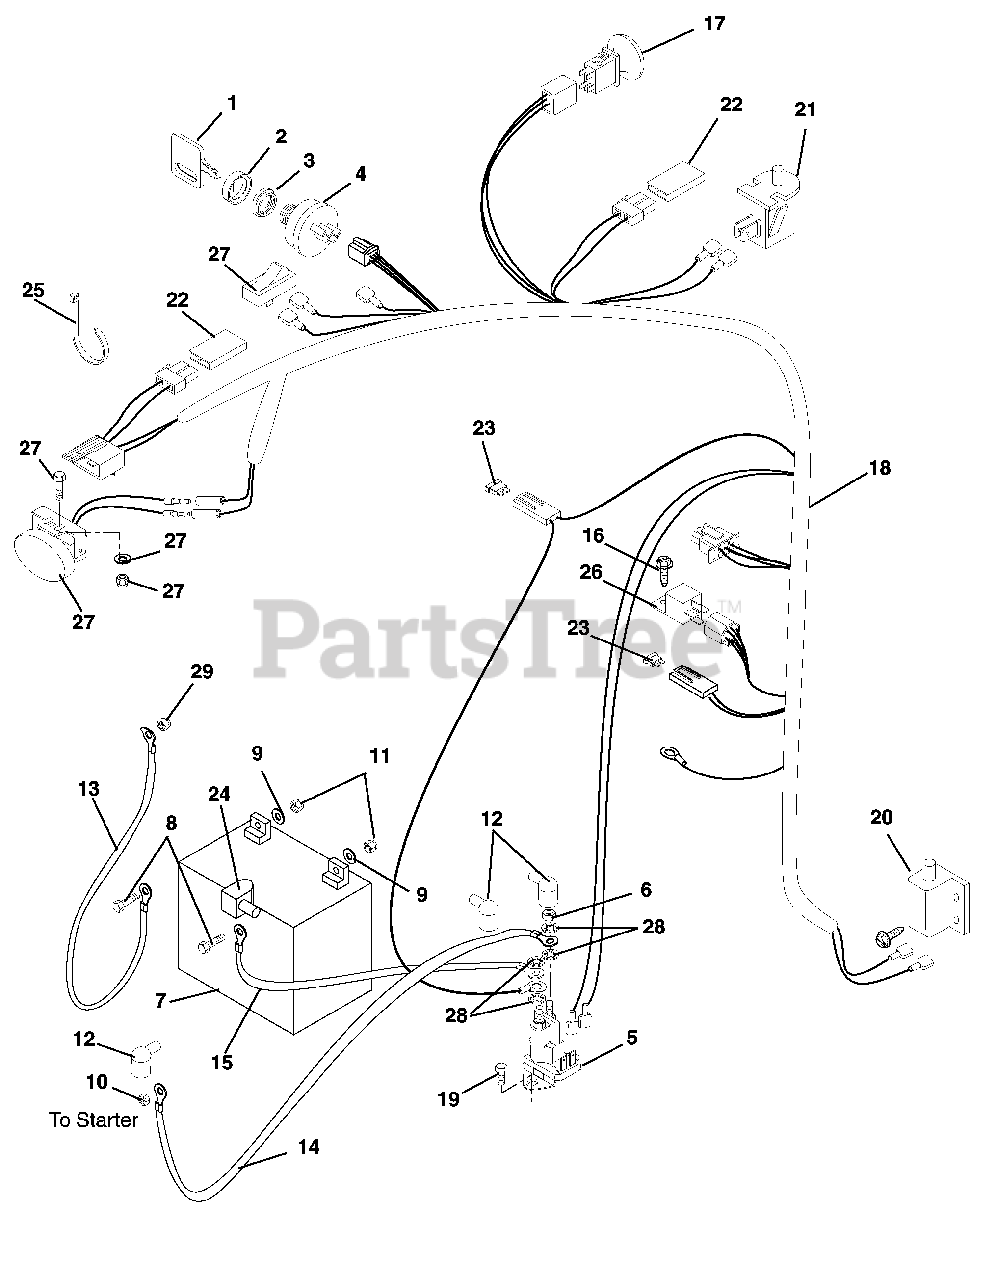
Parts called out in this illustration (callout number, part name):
1	KEY -W/CAP
2	CAP - IGNITION SWITCH
3	NUT- PANEL .562-24 GRECO
4	SWITCH KEY 5Y463A ALT GRDNG
5	SOLENOID
6	NUT-JAM .31-24 YWZC
8	@BLT-HEX .25-20X.75 GR5 YWZC
9	@WSHR-LK .25X.062 REG YWZC
10	@NUT-SPNLK-FLG .25-20 YWZC
11	@NUT-HEX .25-20 YWZC
12	BOOT, EYELET TERMINAL
13	CBL,NEGATIVE BATTERY 20.00
14	STARTER CABLE 13"
15	STARTER CABLE 16"
16	SCR-TAP 10-24X.375 TORX PHD YZ
17	SWITCH, CLUTCH
18	HARNESS-ZOOM SPORT 6PIN
19	@SCR-TAP .25-20X.37 HWH YWZ TR
20	SWITCH- SINGLE POLE N.O.
21	SWITCH- SNAP MTG N.O.
22	DIODE, CONNECTOR SHELL
23	FUSE-25 AMP ATC TYPE
24	INSULATOR
25	CABLE TIE LG 5-1/2
26	RELAY
27	KIT-LIGHT RER/SPORT
28	WSHR-LOCK INT .31 YWZC
29	NUT-LK-TOP-FLG .31-18 BLKZC
